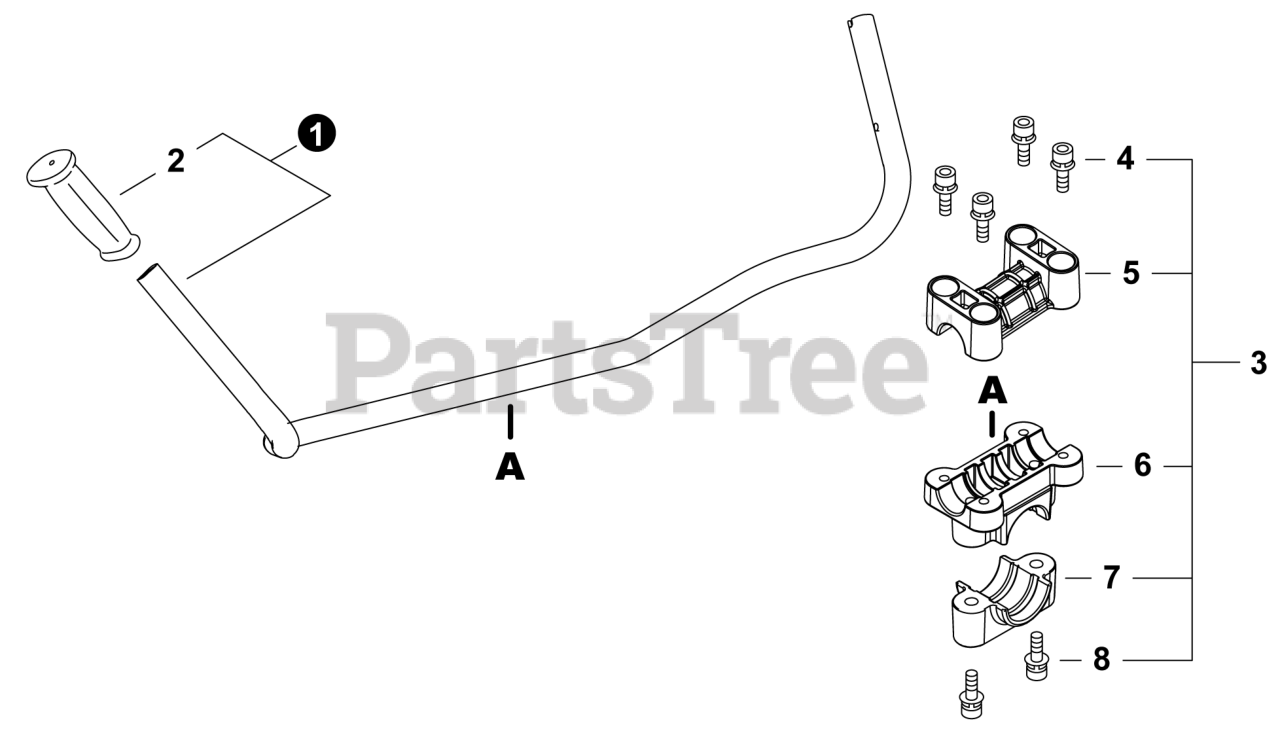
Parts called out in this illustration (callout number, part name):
1	U-HANDLE ASSY
2	GRIP, HANDLE
3	MOUNTING KIT, U-HANDLE
4	BOLT 6x25
5	BRACKET, HANDLE - UPPER
6	BRACKET, HANDLE - LOWER
7	BRACKET, MOUNTING
8	BOLT 6x30
